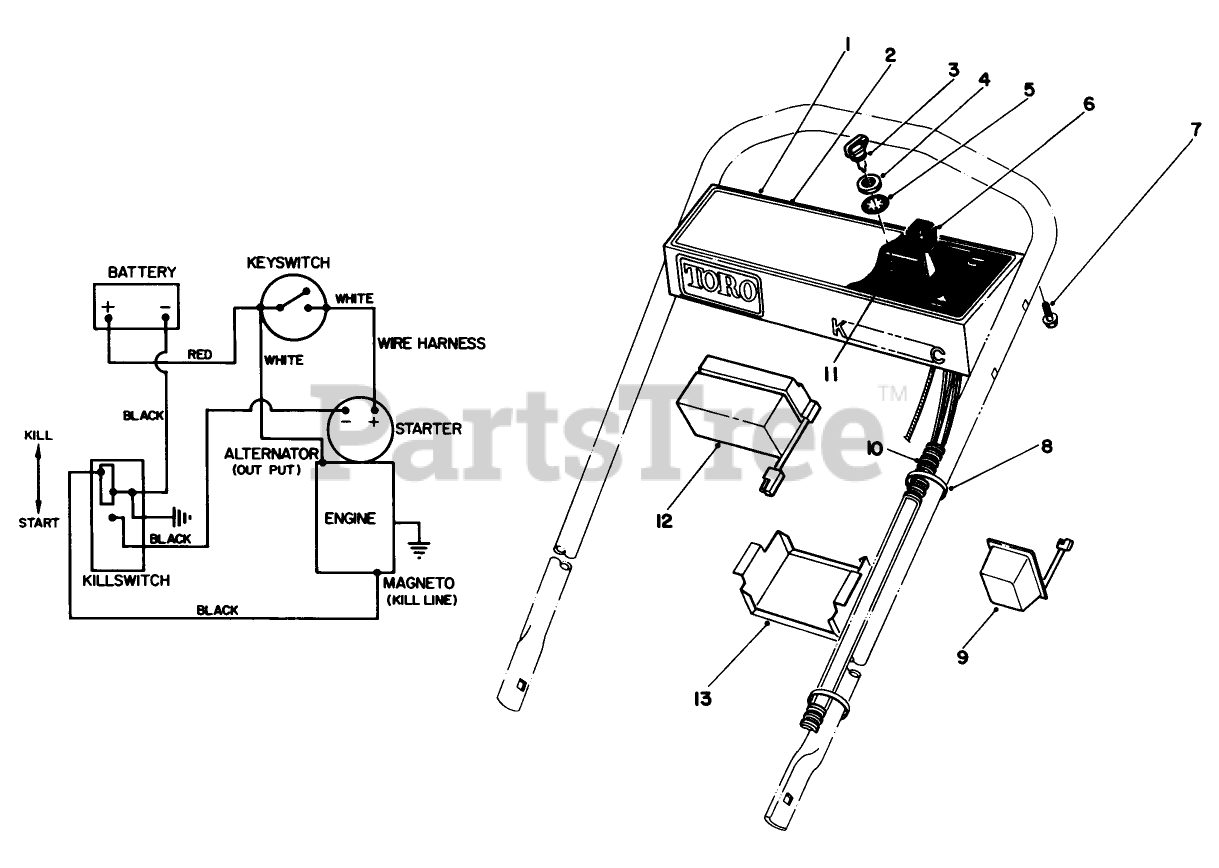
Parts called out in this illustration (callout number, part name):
3	KEY-IGNITION
4	NUT-HH
5	WASHER-LOCK
7	SCREW-HWHTF
8	TIE-CABLE
10	WIRE HARNESS
11	STARTER SWITCH ASM
